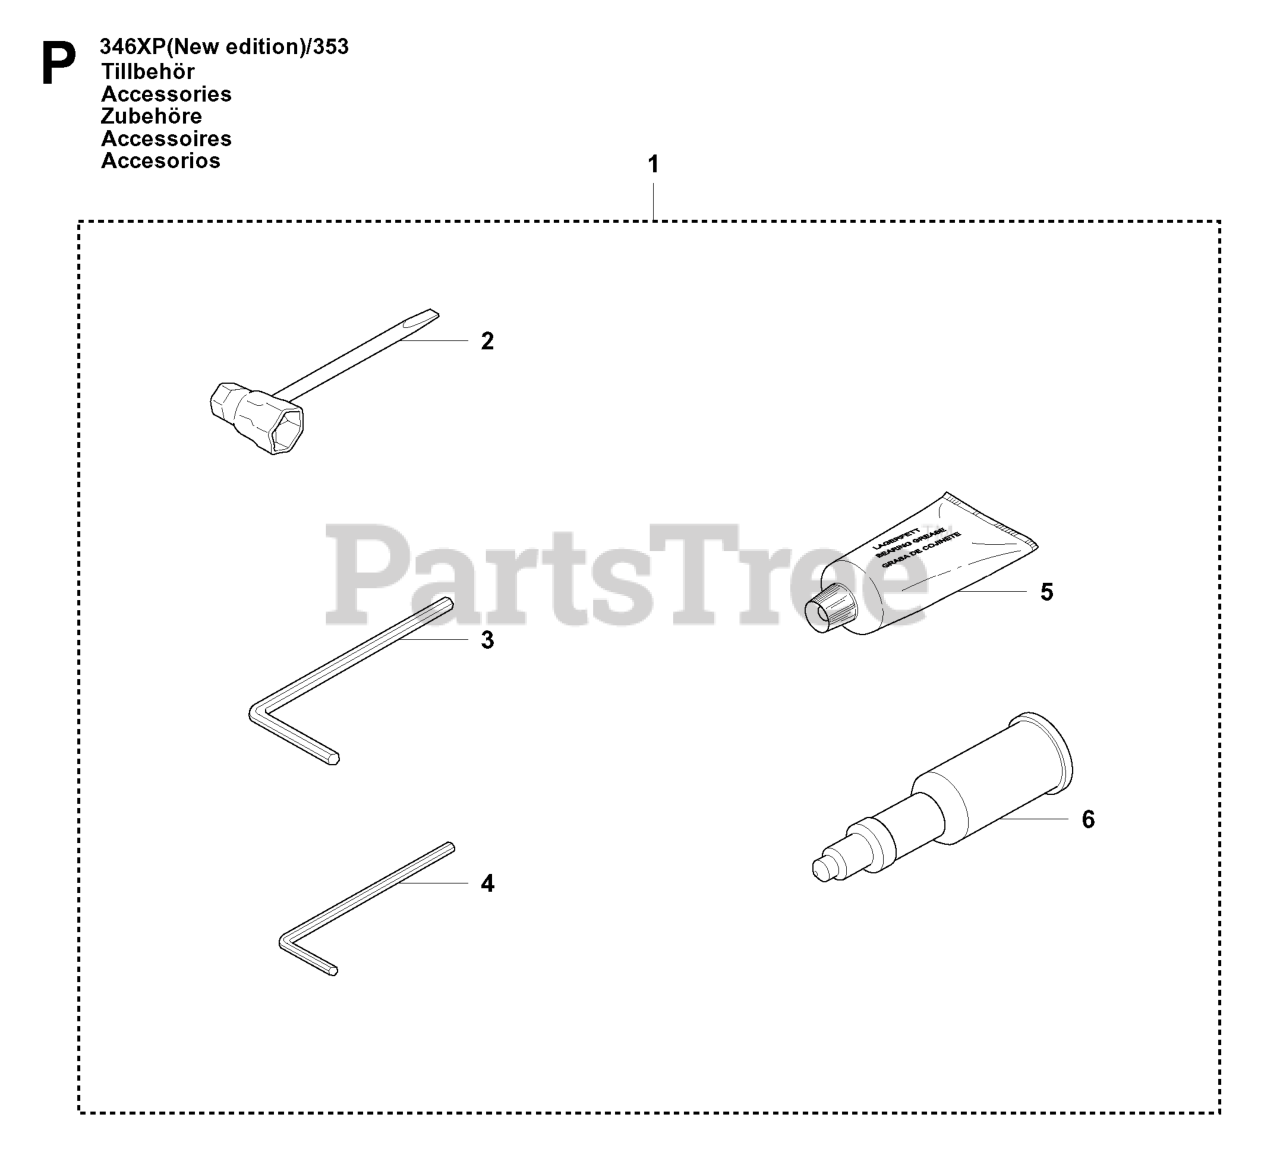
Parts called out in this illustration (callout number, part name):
1	TOOL KIT
2	COMBI TOOL
5	GREASE
6	Grease Gun
